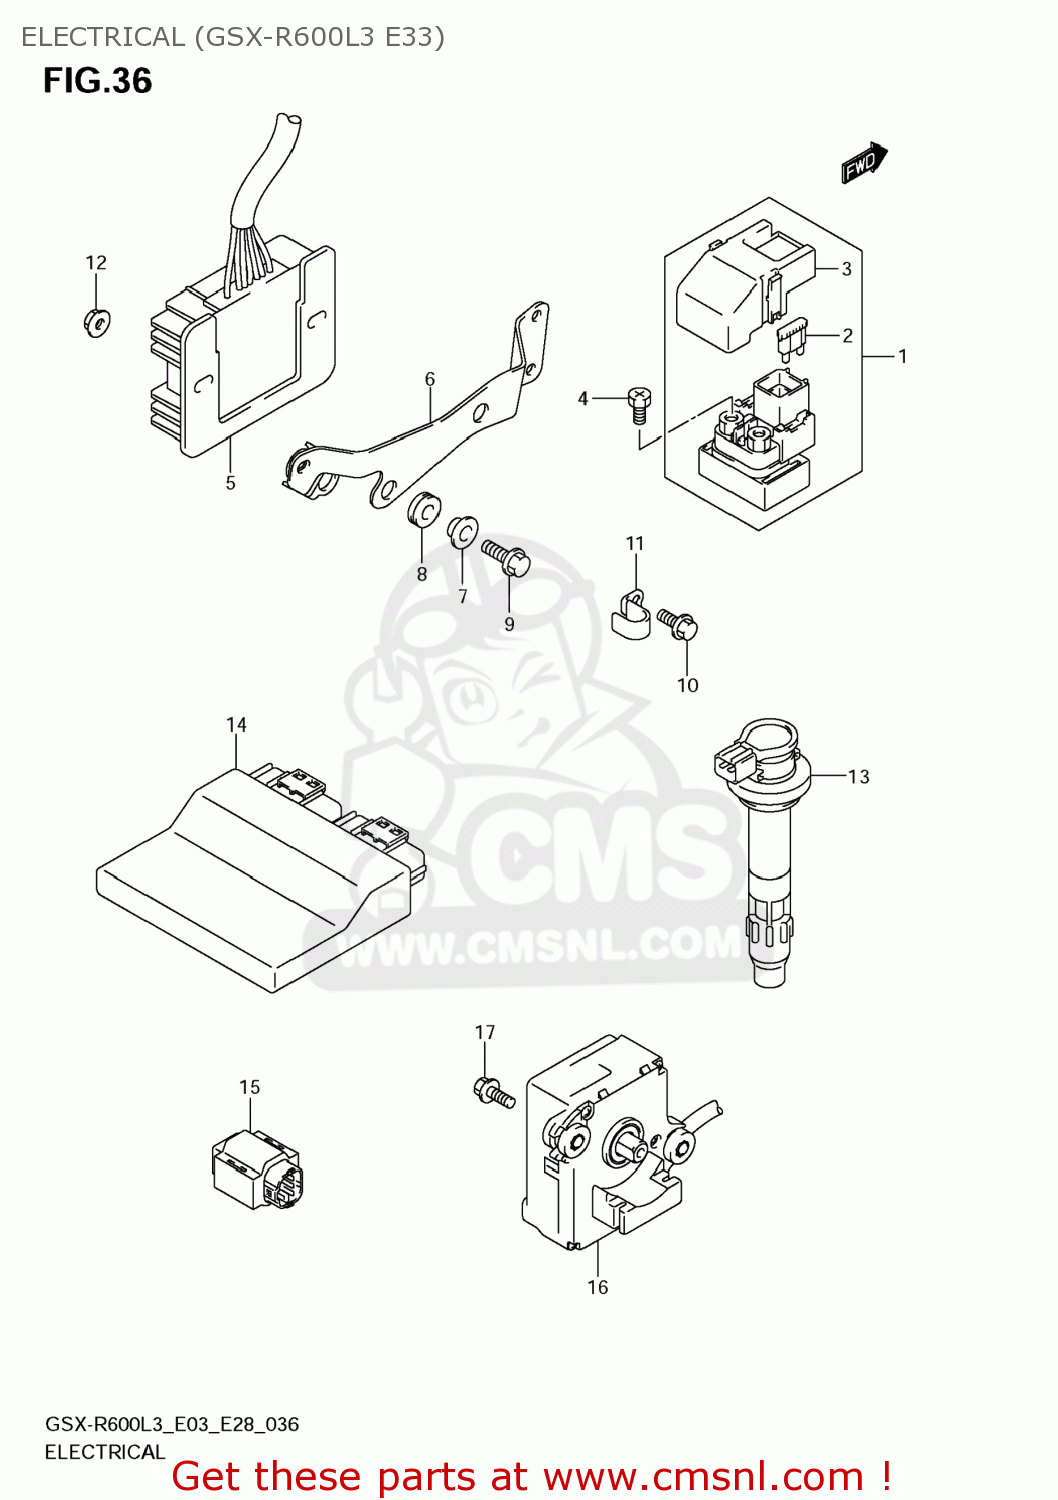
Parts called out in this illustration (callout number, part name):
1	RELAY ASSY,STARTING MOTOR
2	FUSE(30A)
3	COVER
4	SCREW(6X8)
5	RECTIFIER ASSY
6	BRACKET,RECTIFIER
7	SPACER(6.2X8.4X6.9)
8	CUSHION
9	BOLT(6X20)
10	BOLT
11	CLAMP(L:80)
12	NUT
13	COIL ASSY,IGNITION
14	CONTROL UNIT,FI
15	SENSOR ASSY,FUEL CUT
16	ACTUATOR ASSY,EXHAUST CONTROL
17	BOLT(6X32.5)
